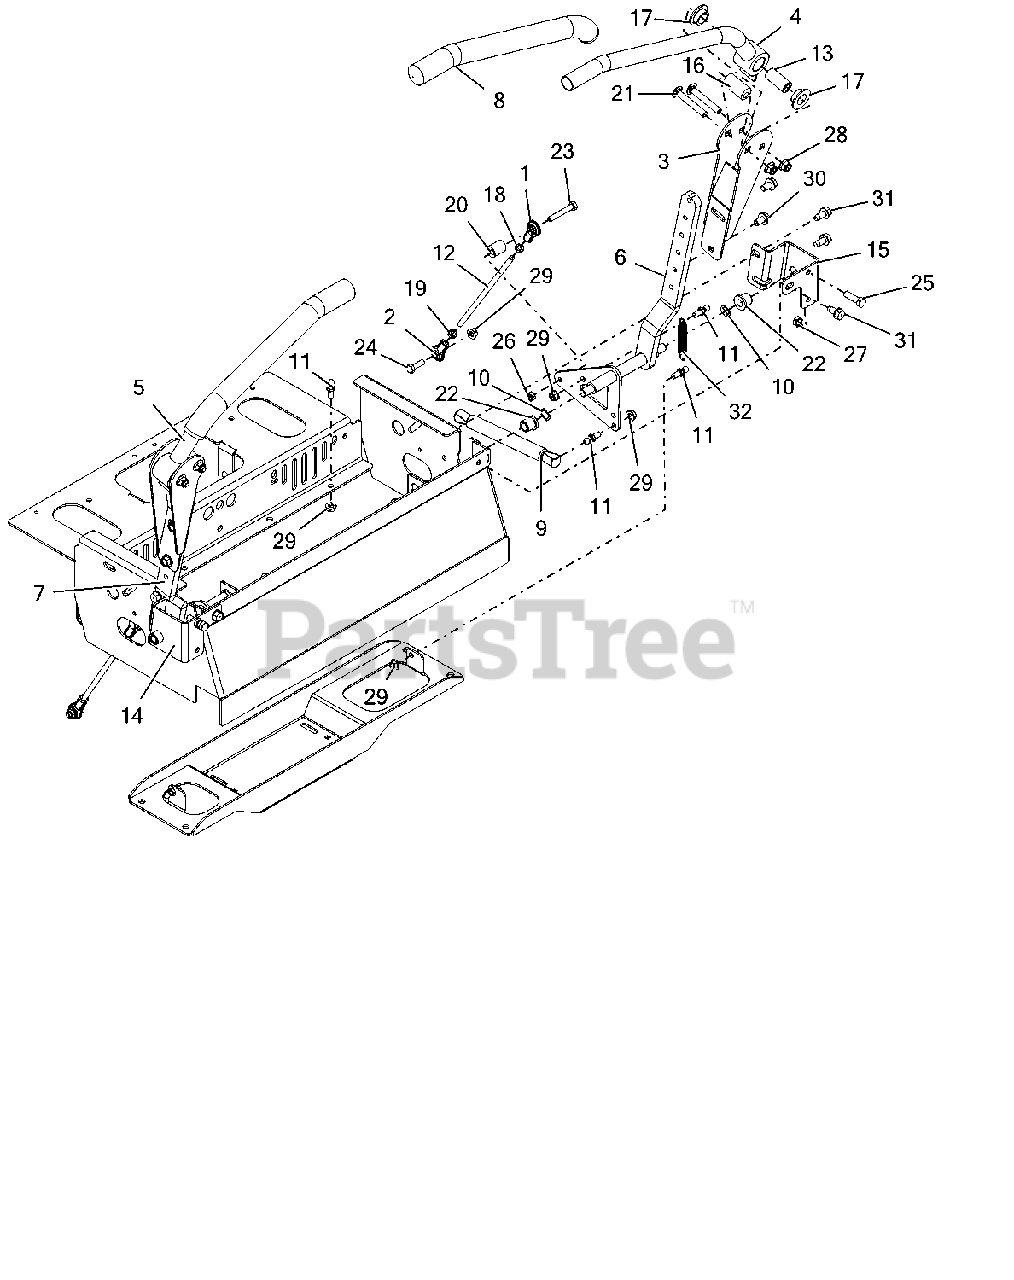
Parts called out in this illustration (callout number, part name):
1	ALIGNABALL, 5/16 RH THREAD
2	ALIGNABALL, 5/16 LH THREAD
3	UPPER ADJ CNTRL ARM WLDMT- BLK
4	WLDMT, LH DRIVE CONTROL HANDLE
5	WLDMT, RH DRIVE CONTROL HANDLE
6	WLDMT, LH LOWER CONTROL ARM
7	WLDMT, RH LOWER CONTROL ARM
8	GRIP, HANDLEBAR
9	DAMPER
10	WAVE WASHER .531X.781X.125FH
11	STUD- BALL
12	ROD, STEERING
13	SPACER, STEERING ARM
14	PT200/400 RH CNTRL STP BRK-RED
15	PT200/400 LH CNTRL STP BRK-RED
16	BSHG, ECCENTRIC.406X.875X1.625
17	BSHG-FLG .762X1.48X.44 NYL
18	NUT-JAM .31-24 YWZC
19	NUT-JAM LH .31-24 YWZC
20	ECCENTRIC
21	BLT-RDHDSQSHK, 38-16X2.50 G5YZ
22	BHSG-FLG .500X.750X.750X.125
23	@BLT-HEX .31-18X2.00 GR5 YWZC
24	@BLT-HEX .31-18X1.00 GR5 YWZC
25	@BLT-HEX .38-16X1.25 GR5 YWZC
26	NUT-LK-CTR .31-18 YWZC
27	NUT-HEX-JAM .375-16 YWZC
28	@NUT-LK-NYL-FLG .38-16 YWZC
29	NUT-LK-TOP-FLG .31-18 YWZC
30	BLT, SCRHFWH .375-16X.625 YWZC
31	@SCR-TAP .38-16X.75 HWH TR YWZ
32	SPRING,EXT,.061X.50X3.0
